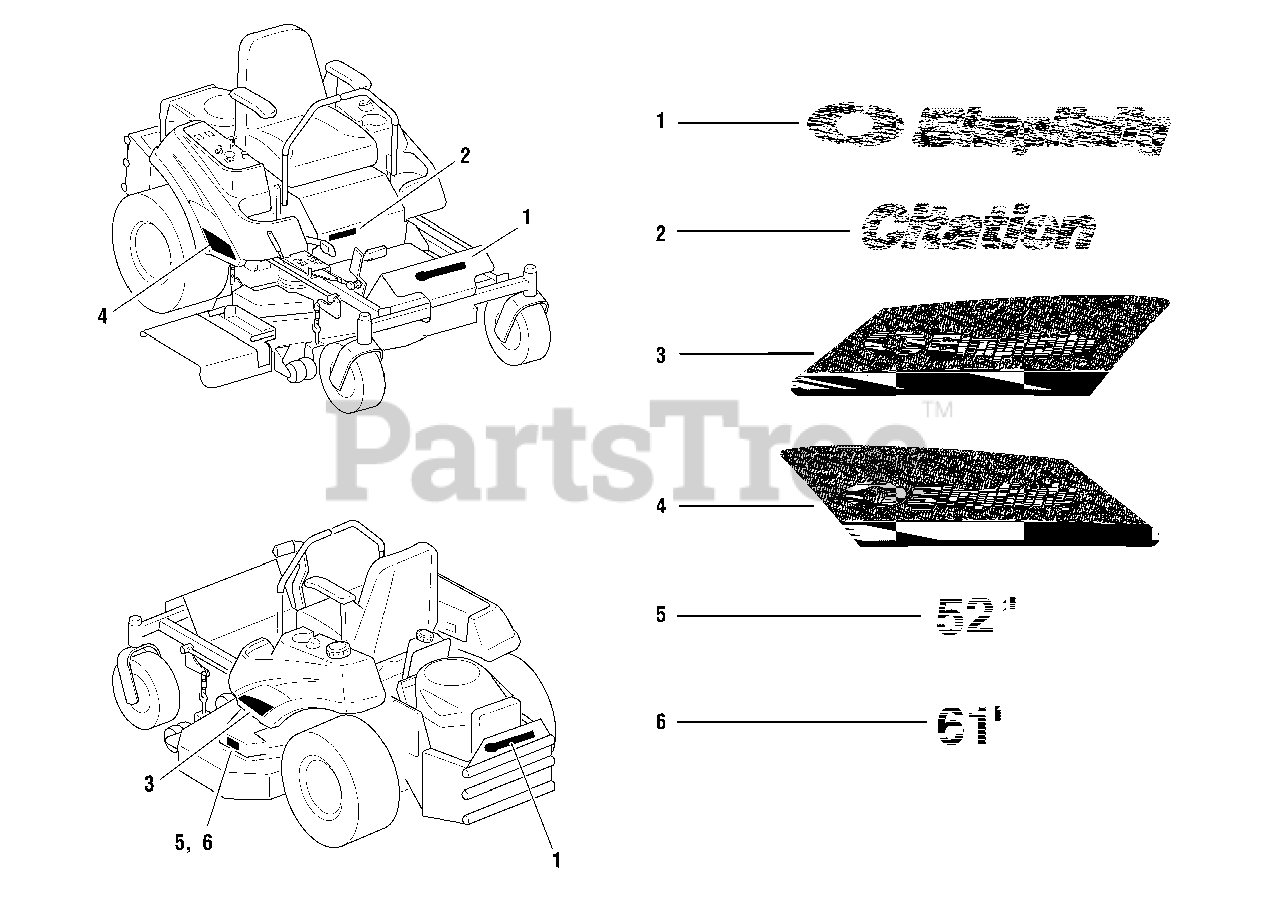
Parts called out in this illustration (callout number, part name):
1	DECAL, Simplicity Logo
2	DECAL, Citation
3	DECAL, Badge, RH
4	DECAL, Badge, LH
5	DECAL, 52"
6	DECAL, 61"
